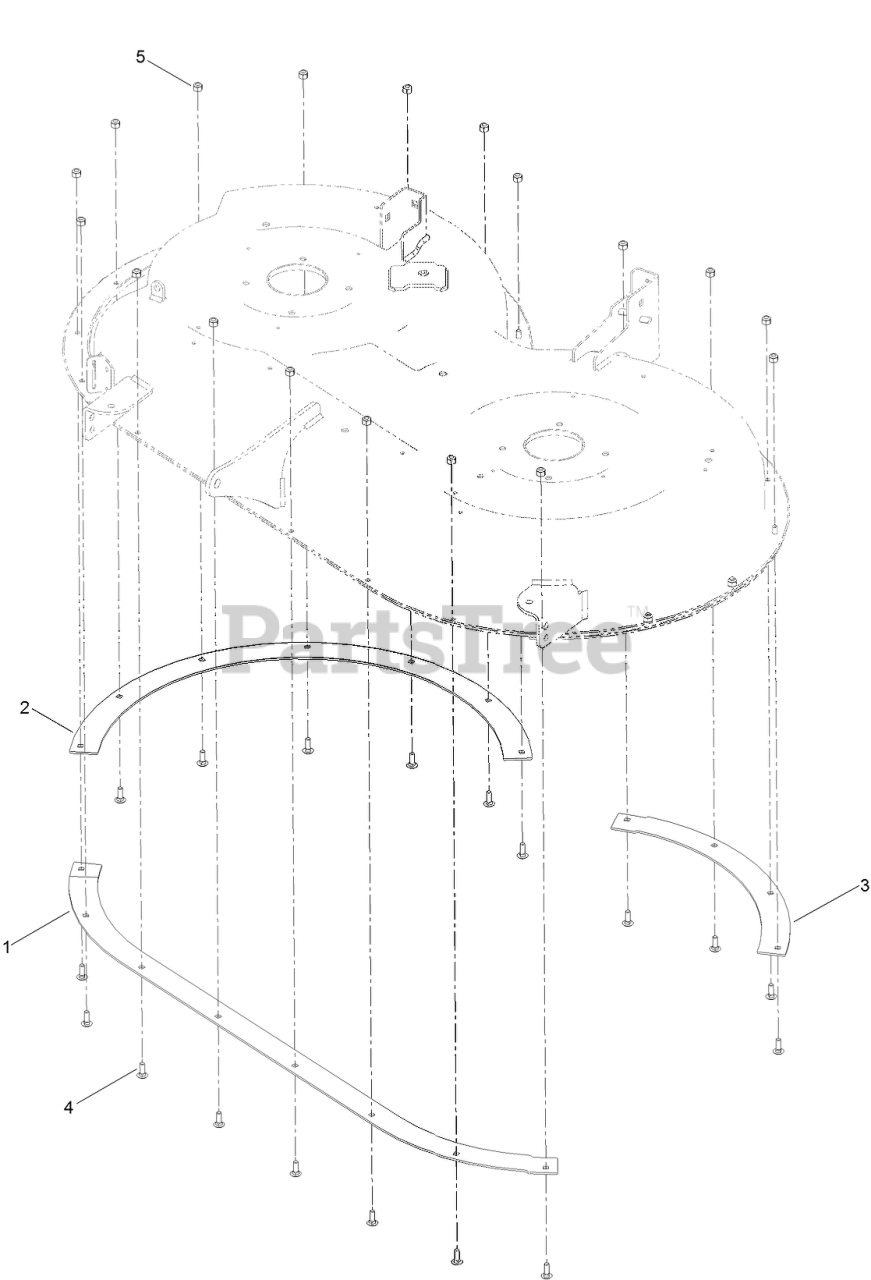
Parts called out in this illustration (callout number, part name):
1	BAFFLE-BLOWOUT, FRONT
2	BAFFLE-BLOWOUT, SIDE
3	BAFFLE-BLOWOUT, SIDE
4	BOLT-CARR
5	NUT-LOCK, NI
